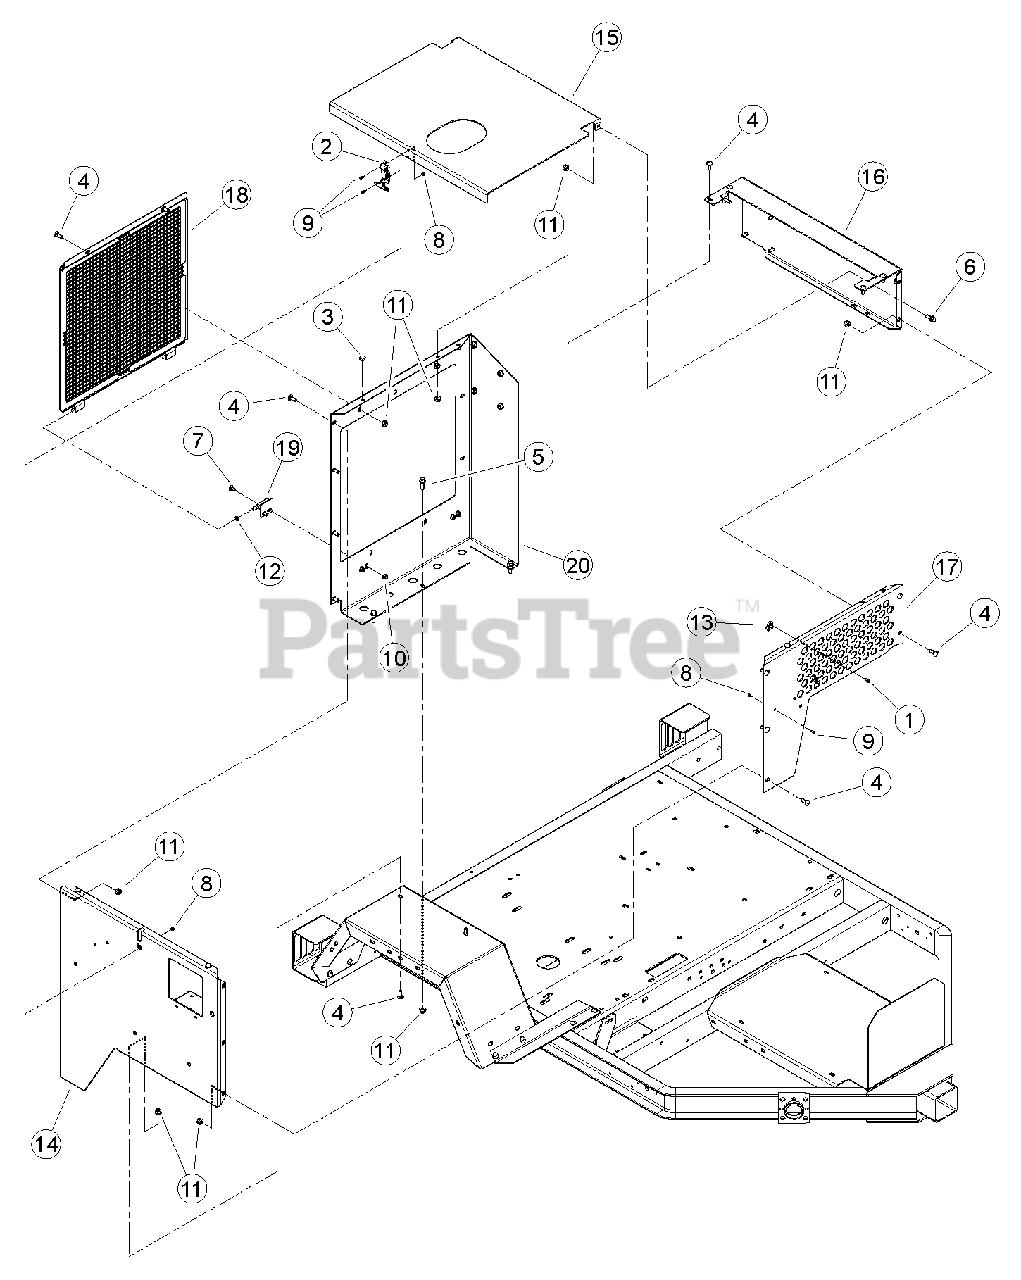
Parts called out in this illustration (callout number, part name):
1	RIVET, 1/4 X 3/4 ST POP
2	LATCH, FLEXIBLE DRAW
3	BUMPER, RUBBER
4	BOLT, 3/8 X 1" GR5 CRG NC ZP
5	BOLT, 3/8 X 1-1/4 FLANGE NC
6	BOLT, 3/8 X 1 FLANGE NC
7	BOLT, 5/16 X 3/4 GR5 CRG NC ZP
8	NUT, 10/24 NYLOCK TYPE NM ZP
9	SCREW, MCH 10-24 X 1/2" PAN HD PH ZP
10	NUT, 5/16-18 NYLOCK-FLANGE
11	NUT, 3/8-16 NYLOCK FLANGE
12	HINGE, REF 18282-00
13	CLAMP, CABLE MOUNT
14	WELDMENT, SIDE COVER PANEL
15	HOOD, ENGINE
16	SIDE, ENGINE COVER
17	COVER, REAR ENGINE
18	WELDMENT, ENGINE SCREEN
19	WELDMENT, SCREEN HINGE
20	PANEL, RADIATOR COVER
